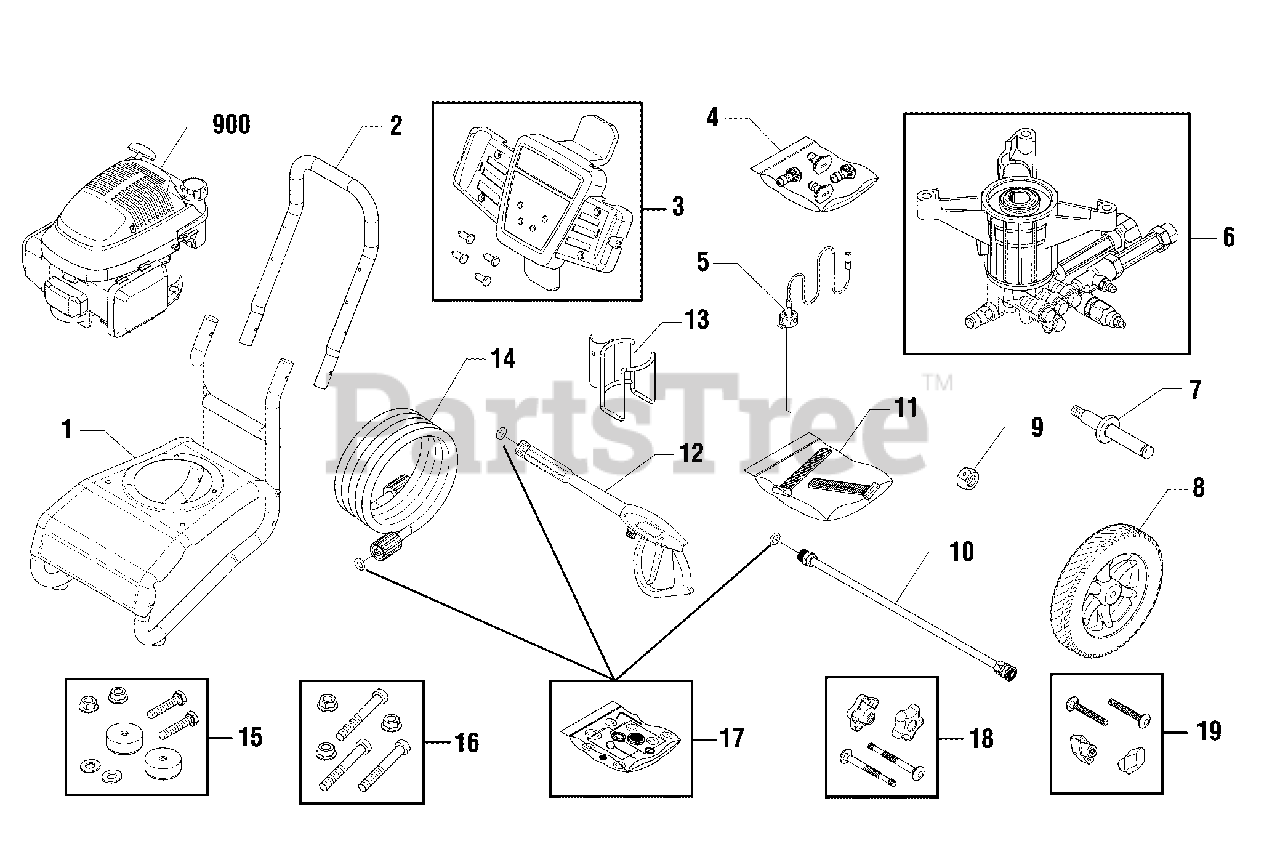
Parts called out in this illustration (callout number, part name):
4	KIT-QC NOZZLE
10	EXTENSION-QC
12	GUN
14	HOSE
15	MOUNT-VIBRATION
16	KIT-HARDWARE PUMP MOUNTING
900	** ENGINE
